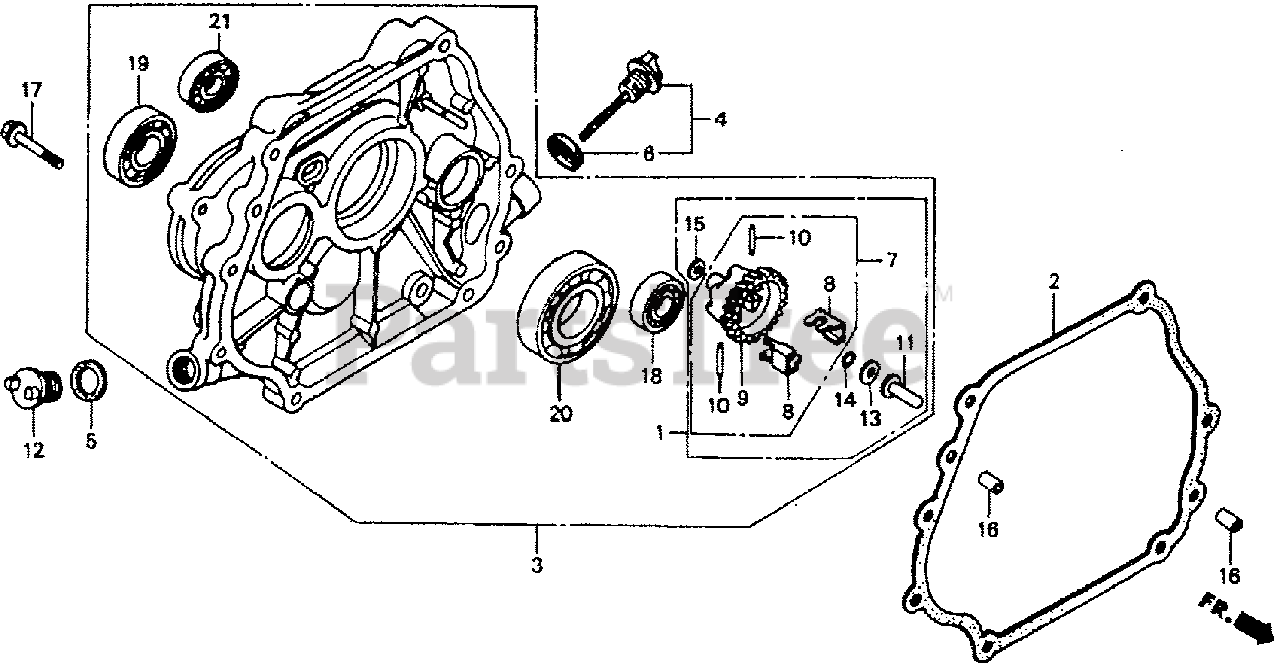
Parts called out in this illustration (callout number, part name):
1	GOVERNOR KIT (BALANCER) (Honda Code 3313665). (NOT AVAILABLE)
1	GOVERNOR KIT (BALANCER)
2	GASKET, CASE COVER
3	COVER ASSY., CRANKCASE (Honda Code 2333037). (L-TYPE)(BALANCER)
3	COVER ASSY., CRANKCASE (Honda Code 4049078). (L-TYPE)(BALANCER)
3	COVER ASSY., CRANKCASE (Honda Code 7185580). (L-TYPE)(BALANCER)
4	CAP ASSY., OIL FILLER
5	GASKET, OIL FILLER CAP
6	GASKET, OIL FILLER CAP
7	GOVERNOR ASSY. (BALANCER)
8	WEIGHT, GOVERNOR
9	HOLDER, GOVERNOR WEIGHT
10	PIN, GOVERNOR WEIGHT
11	SLIDER, GOVERNOR
12	CAP, OIL FILLER
12	CAP, OIL HOLE
13	CAP, OIL FILLER
13	WASHER (6X16)
14	CLIP, GOVERNOR HOLDER
15	WASHER, PLAIN (6MM)
16	PIN, DOWEL (8X12)
16	PIN A, DOWEL (8X12)
17	BOLT, FLANGE (8X35)
18	BEARING, RADIAL BALL (6202)
19	BEARING, RADIAL BALL (6204)
20	BEARING, RADIAL BALL (6206)
